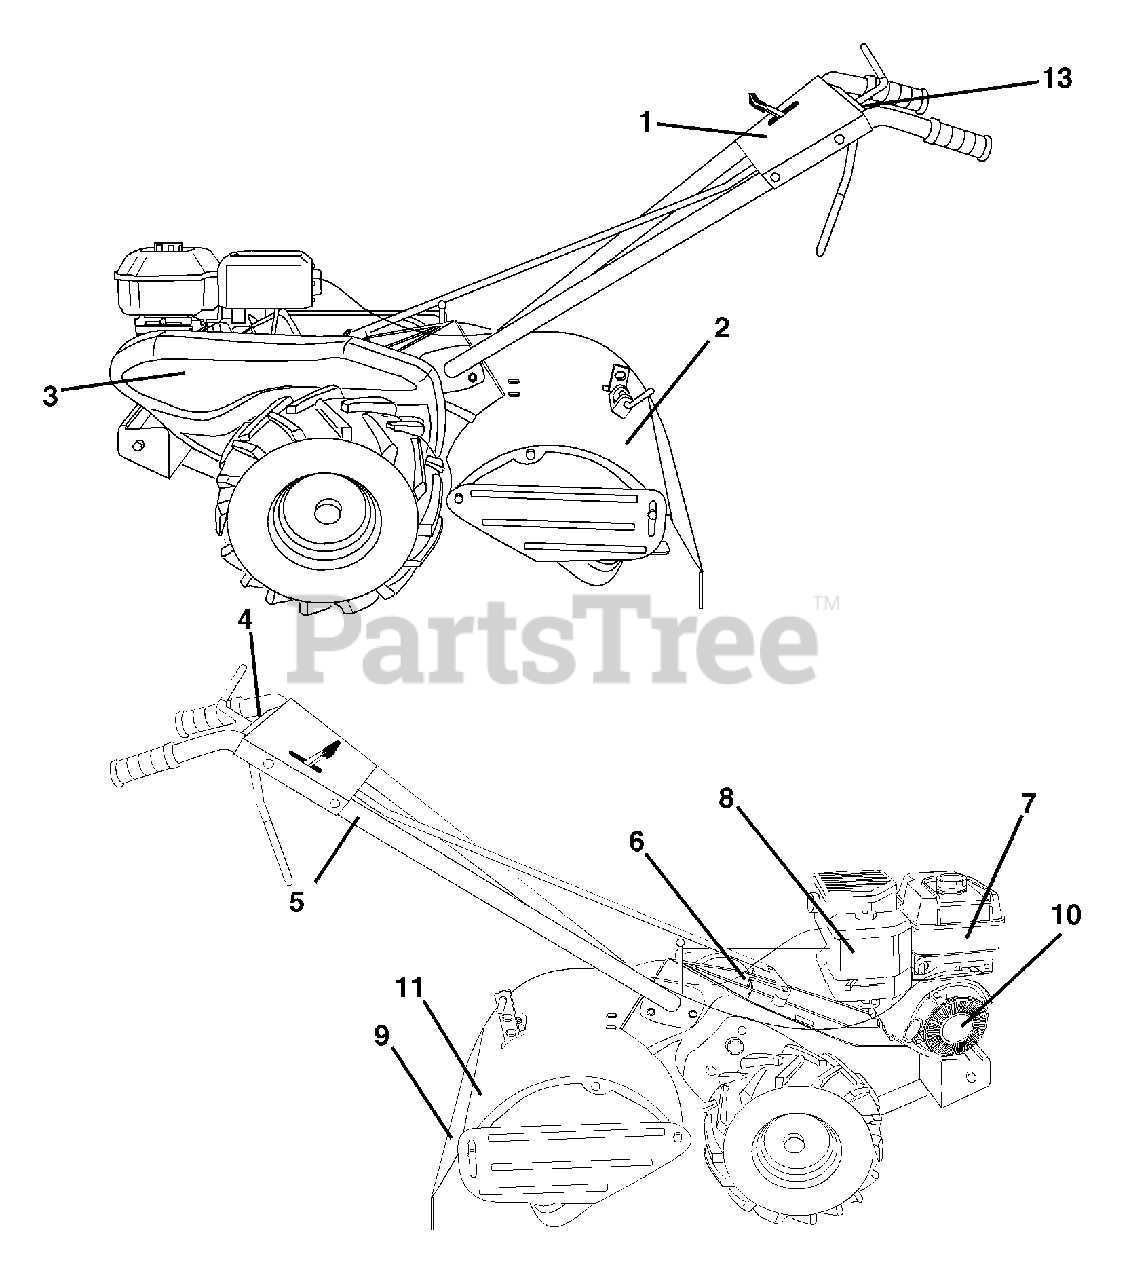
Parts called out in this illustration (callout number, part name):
1	Decal, Control Panel (Statesman)
1	Decal, Control Panel (Agway)
2	Decal, Warning
3	Decal, Belt Guard (Statesman)
3	Decal, Belt Guard (Agway)
4	Decal, Instruction, Tilling
5	Decal, Hand Placement
6	Decal, Shift Indicator
7	Decal, OHV N-I/C 190CELBL
8	Decal, Briggs & Stratton
9	Decal, Warning
10	Decal, Rewind INTEK
13	Decal, Control Panel Reverse
